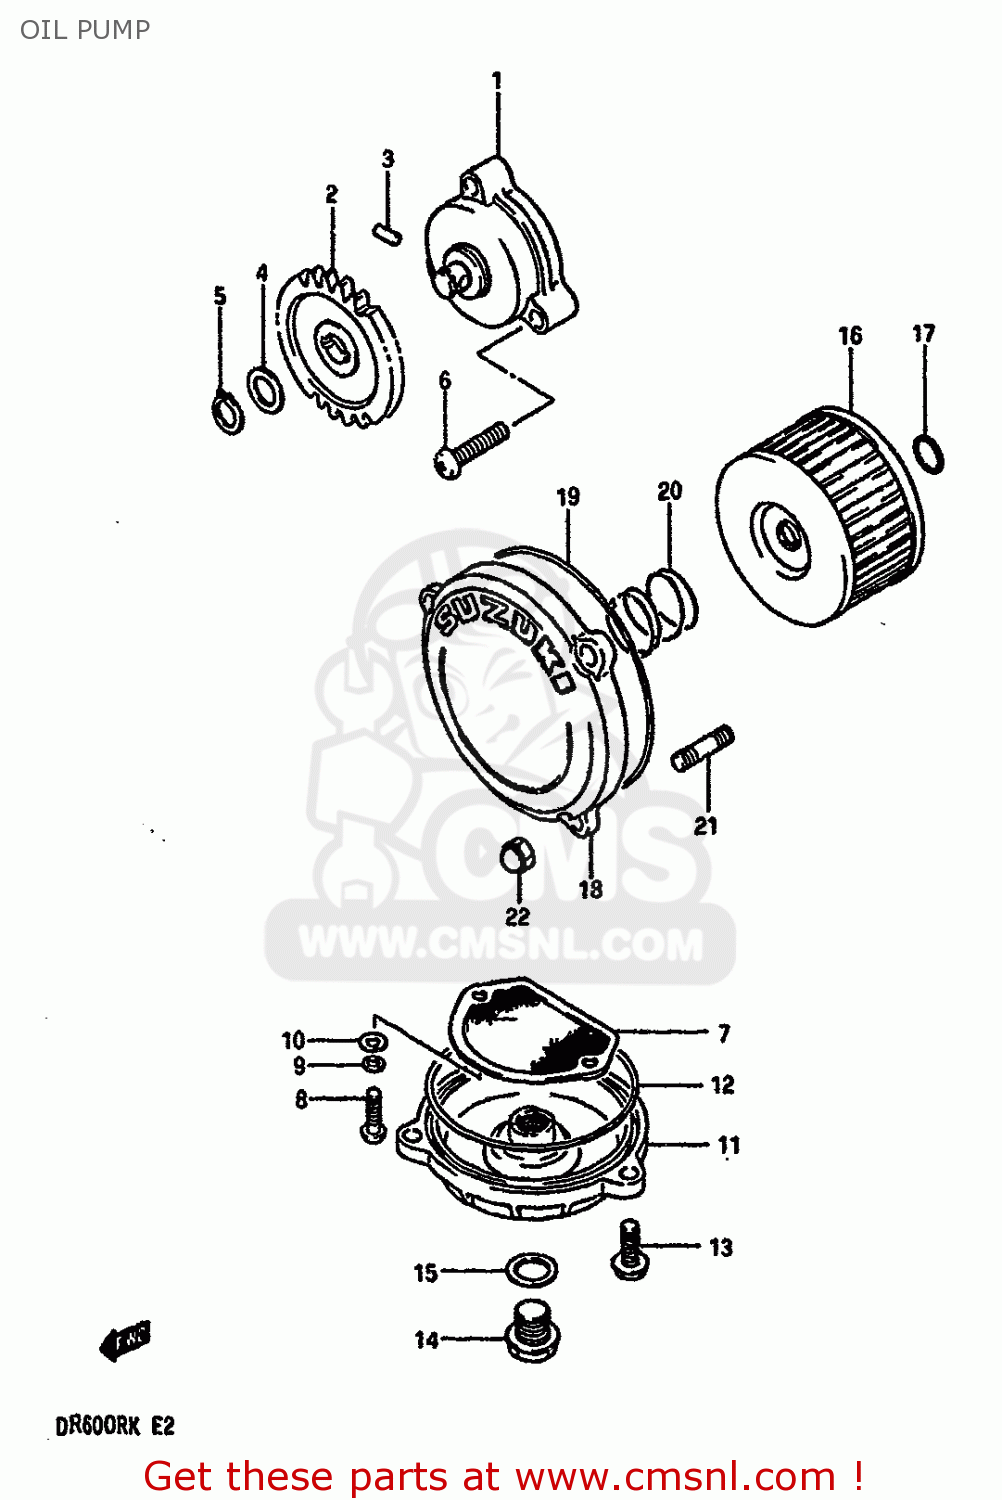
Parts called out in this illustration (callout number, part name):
1	PUMP ASSY,ENGINE OIL
2	GEAR,OIL PUMP DRIVEN
3	PIN(4X15.8)
4	SHIM
5	CIRCLIP
6	SCREW
7	STRAINER,ENGINE OIL
8	SCREW 5X12
9	LOCK WASHER
10	WASHER
11	CAP,OIL STRAINER
12	O RING(D:2.4,ID:85)
13	BOLT,REAR
14	PLUG
15	GASKET(14X19.2X2) (NAS)
16	FILTER,ENGINE OIL
17	O RING(D:2.4,ID:15.8)
18	CAP,OIL FILTER
19	O RING(D:2.4,ID:73)
20	SPRING
21	STUD 6X12
22	NUT 6MM
